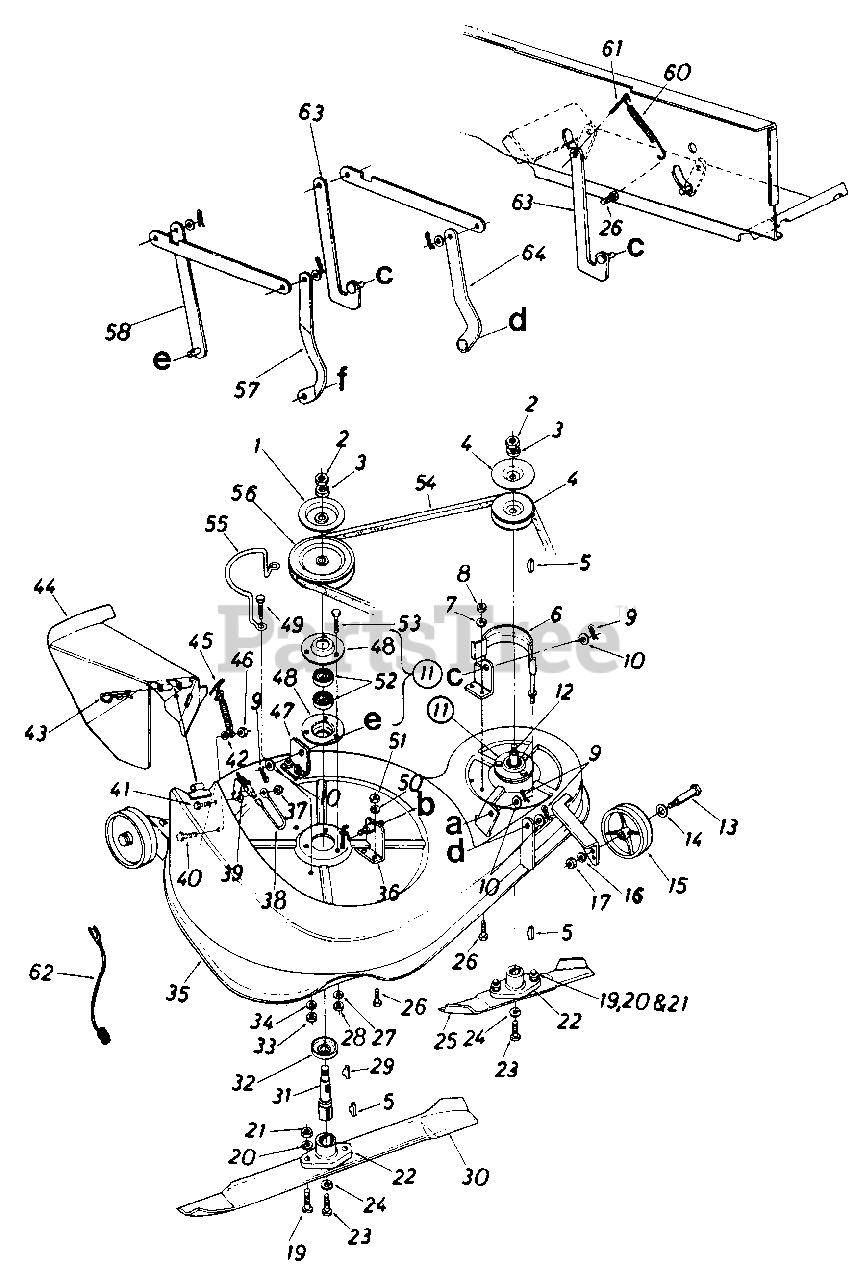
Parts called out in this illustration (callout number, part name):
1	Brake Disc
2	Hex Jam Nut 5/16-18 Thd*
3	Bell-Wash. .630" I.D. x 1.25" O.D.
4	Pulley Ass'y. 3.5" O.D. x 5/8
5	# Hi-Pro Key 5/32" x 5/8" Dia.
6	Belt Guard Ass'y. L.H.
7	L-Wash. 5/16" I.D*
8	Hex Nut 5/16-18 Thd*
9	Internal Cotter Pin /2" Dia.
10	Fl-Wash. .531" I.D. x .93" O.D.
11	Blade Spindle Ass'y.
12	Blade Spindle
13	Shld. Bolt .498" Dia. x 1.635
14	Bell-Wash. .400" I.D. x .88"
15	Deck Wheel 5.0" x 1.38"
16	L-Wash. 5/16" I.D*
17	Hex Nut 3/8-16 Thd*
19	Hex Bolt 5/16-24 x 1.00" Lg. (Grade 5)
20	L-Wash. 5/16" I.D*
21	Hex Nut 5/16-24 Thd*
22	Blade Adapter
23	Hex Bolt 3/8-24 x 1.50" Lg. (Grade 5)
24	L-Wash. 3/8" I.D. H.D.
26	Hex Bolt 5/16-18 x .75" Lg*
27	L-Wash. 5/16" I.D*
28	Hex Nut 5/16-18 Thd*
29	#6 Hi-Pro Key 5/32" x 5/8" Dia.
31	Blade Spindle
32	Bearing Shield
33	Hex Nut 5/16-18 Thd*
34	L-Wash. 5/16" I.D*
35	36" Deck Ass'y.
36	Deck Hanger Brkt. R.H. Front
37	Hex Nut 1/4-20 Thd*
39	Safety Switch
40	Truss Mach. Scr. 1/4-20 x .50" Lg.
41	Hex Bolt 1/4-20 x .50" Lg.
42	Fl-Wash. .281" I.D. x 50" O.D.
43	Internal Cotter Pin
44	Chute Deflector Ass'y.
45	Spring Latch Ass'y.
46	Hex Nut 1/4-20 Thd.
47	Deck Hanger Brkt. R.H. Rear
48	Brg. Housing 1.85" I.D.
49	Hex Bolt 5/16-18 x .75" Lg.
50	L-Wash. 5/16" I.D.
51	Hex Nut 5/16-18 Thd.
52	Ball Brg. .787" I.D. x 1.85" O.D.
53	Hex Bolt 5/16-18 x 75n Lg.
54	"V"-Belt 1/2" x 71" Lg.
56	Pulley 6.0" O.D. x 5/8"
57	Link Deck Hanger Front R.H.
58	Link Deck Hanger Ass'y. Rear R.H.
61	Cotter Pin 1/8" Dia. x 1.25" Lg.
62	Wire Lead
63	Link Deck Hanger Ass'y. Rear L.H.
64	Link Deck Hanger Ass'y. Front L.H.
